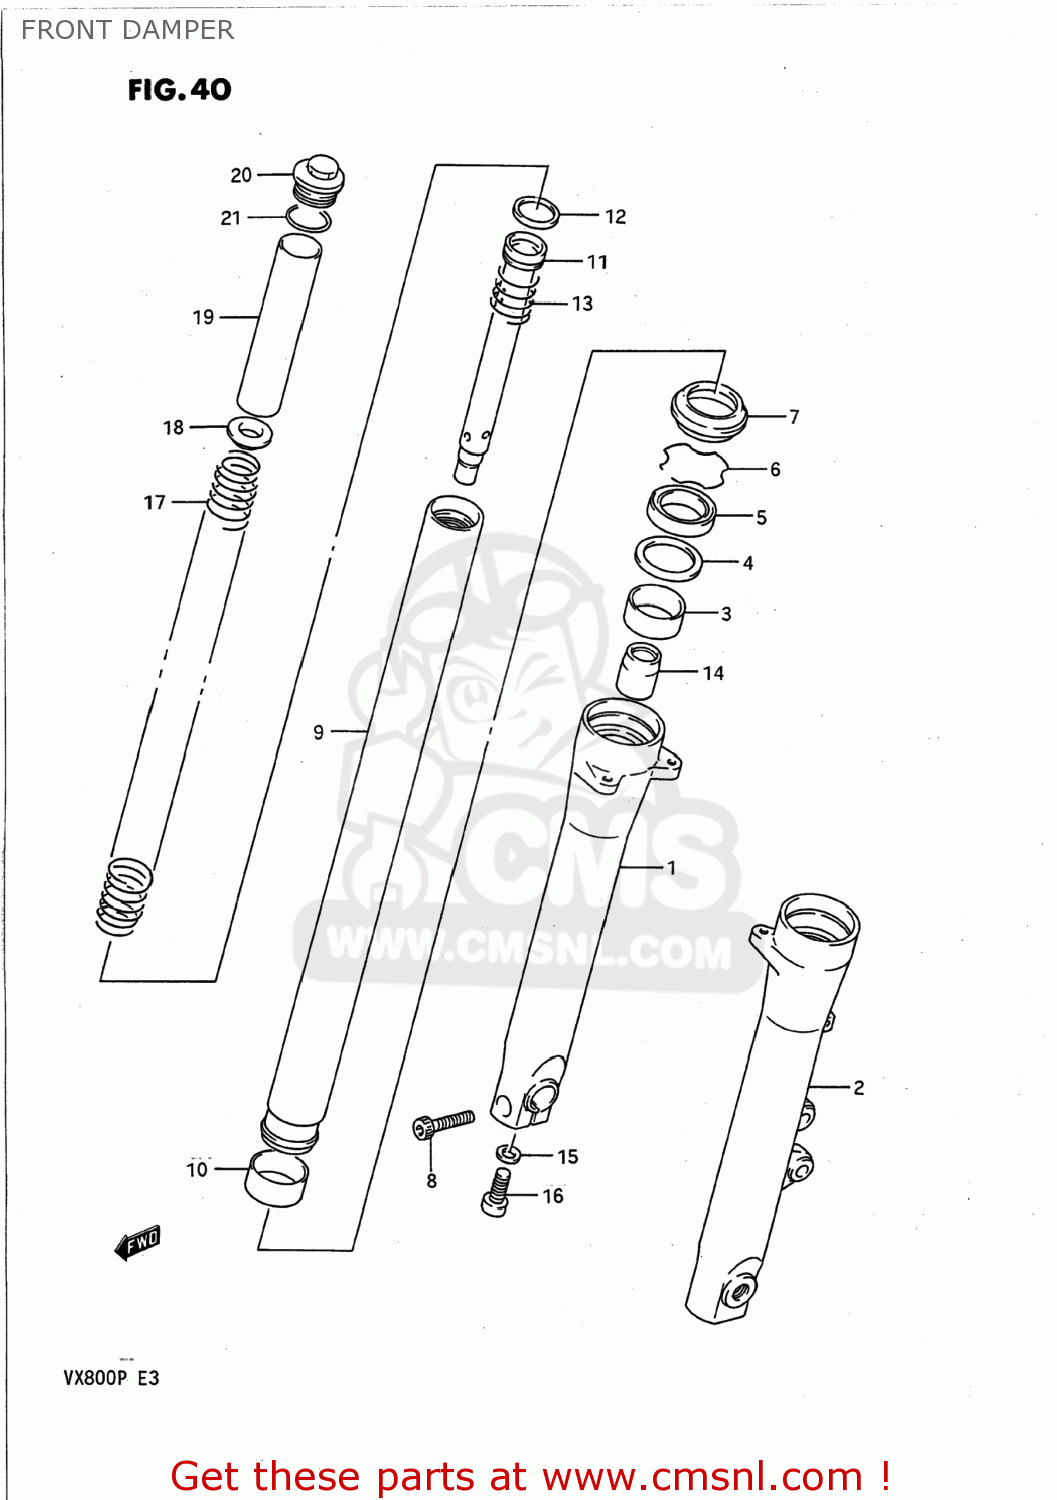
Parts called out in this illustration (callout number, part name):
1	TUBE,OUTER,RIGHT
2	TUBE,OUTER,LEFT
3	METAL,SLIDE
4	WASHER,FORK OIL SEAL
5	OIL SEAL,FRONT FORK
6	RING,OIL SEAL STOPPER
7	DUST SEAL,FRONT FORK
8	BOLT
9	TUBE,INNER
10	PISTON
11	CYLINDER
12	RING,PISTON
13	SPRING,REBOUND
14	PIECE,OIL LOCK
15	GASKET (NAS)
16	BOLT,FORK CYLINDER(10X25)
17	SPRING,MAIN
18	GUIDE,SPRING
19	SPACER,SPRING
20	CAP,FORK
21	O RING
